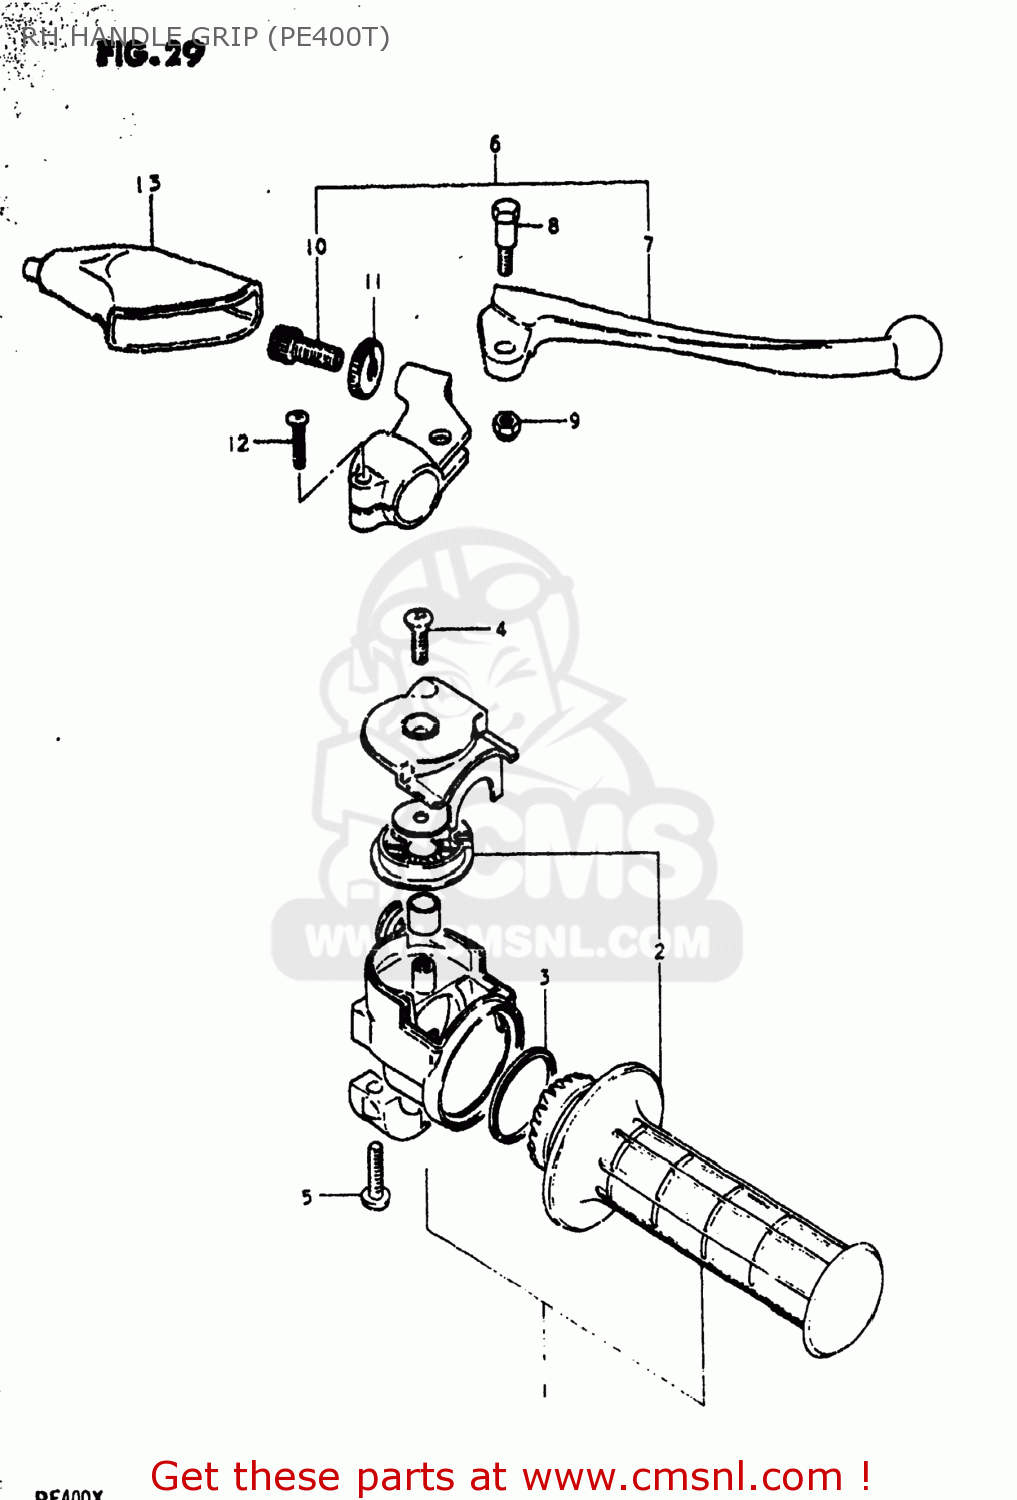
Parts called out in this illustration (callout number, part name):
1	CASE ASSEMBLY,THROTTLE
2	GRIP SET,THROTTLE
3	V-RING,THROTTLE GRIP
4	SCREW
5	SCREW 5X20
6	LEVER ASSY,BRAKE
7	LEVER,BRAKE
8	BOLT,LEVER
9	NUT 6MM
10	ADJUSTER,CABLE
11	NUT,CABLE ADJUSTER
12	SCREW
13	COVER,CLUTCH LEVER
